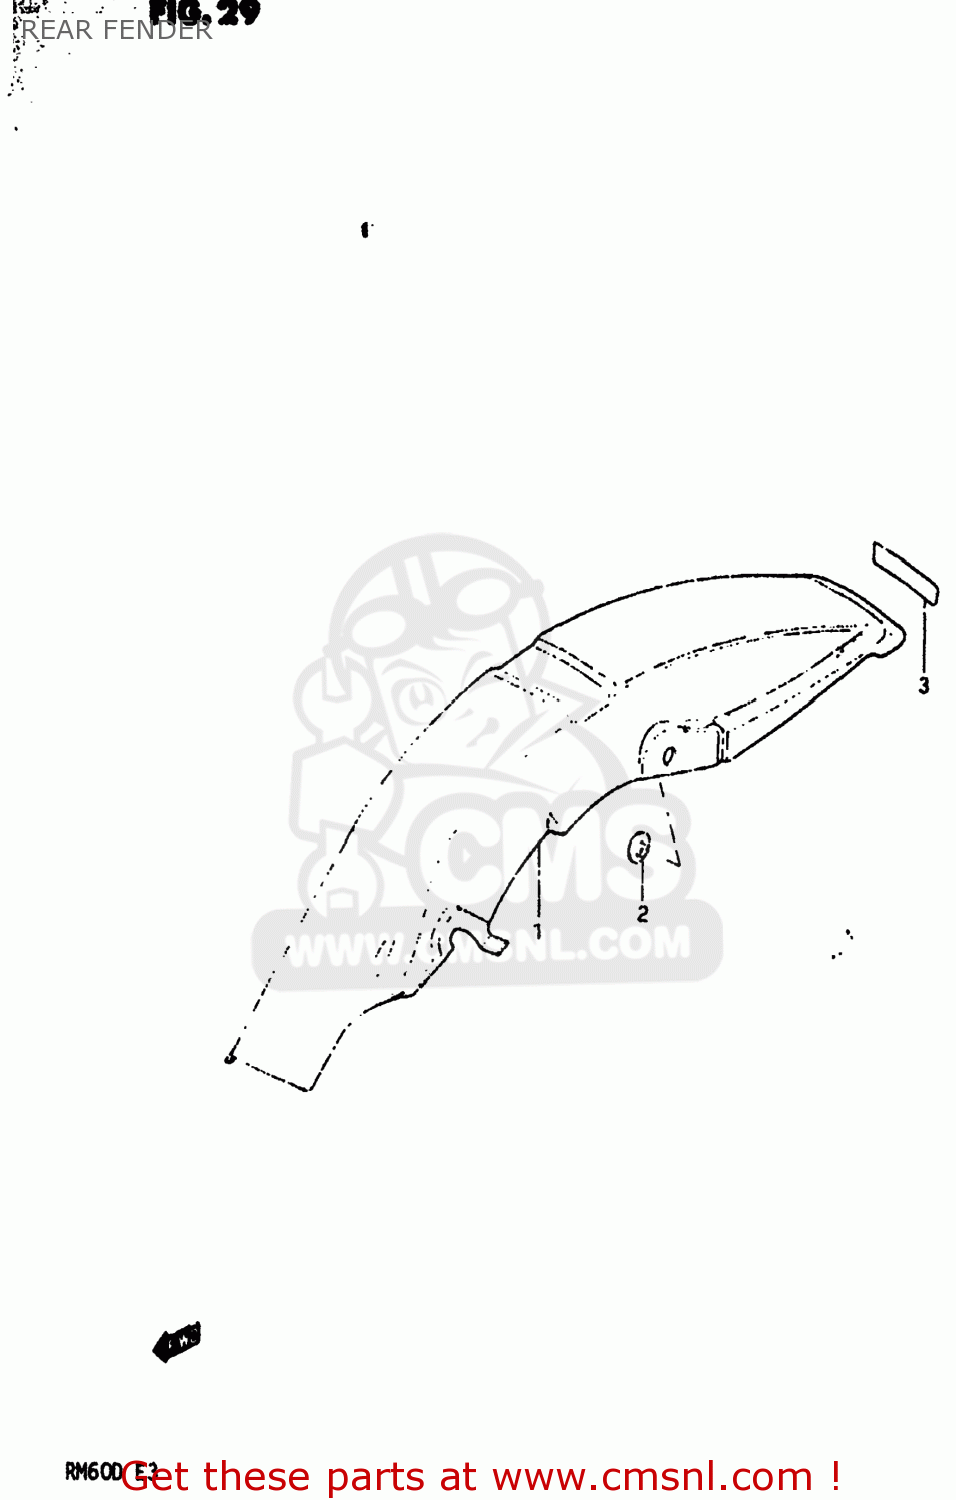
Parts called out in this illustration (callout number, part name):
1	FENDER,REAR
2	WASHER
3	EMBLEM,FRONT FENDER
